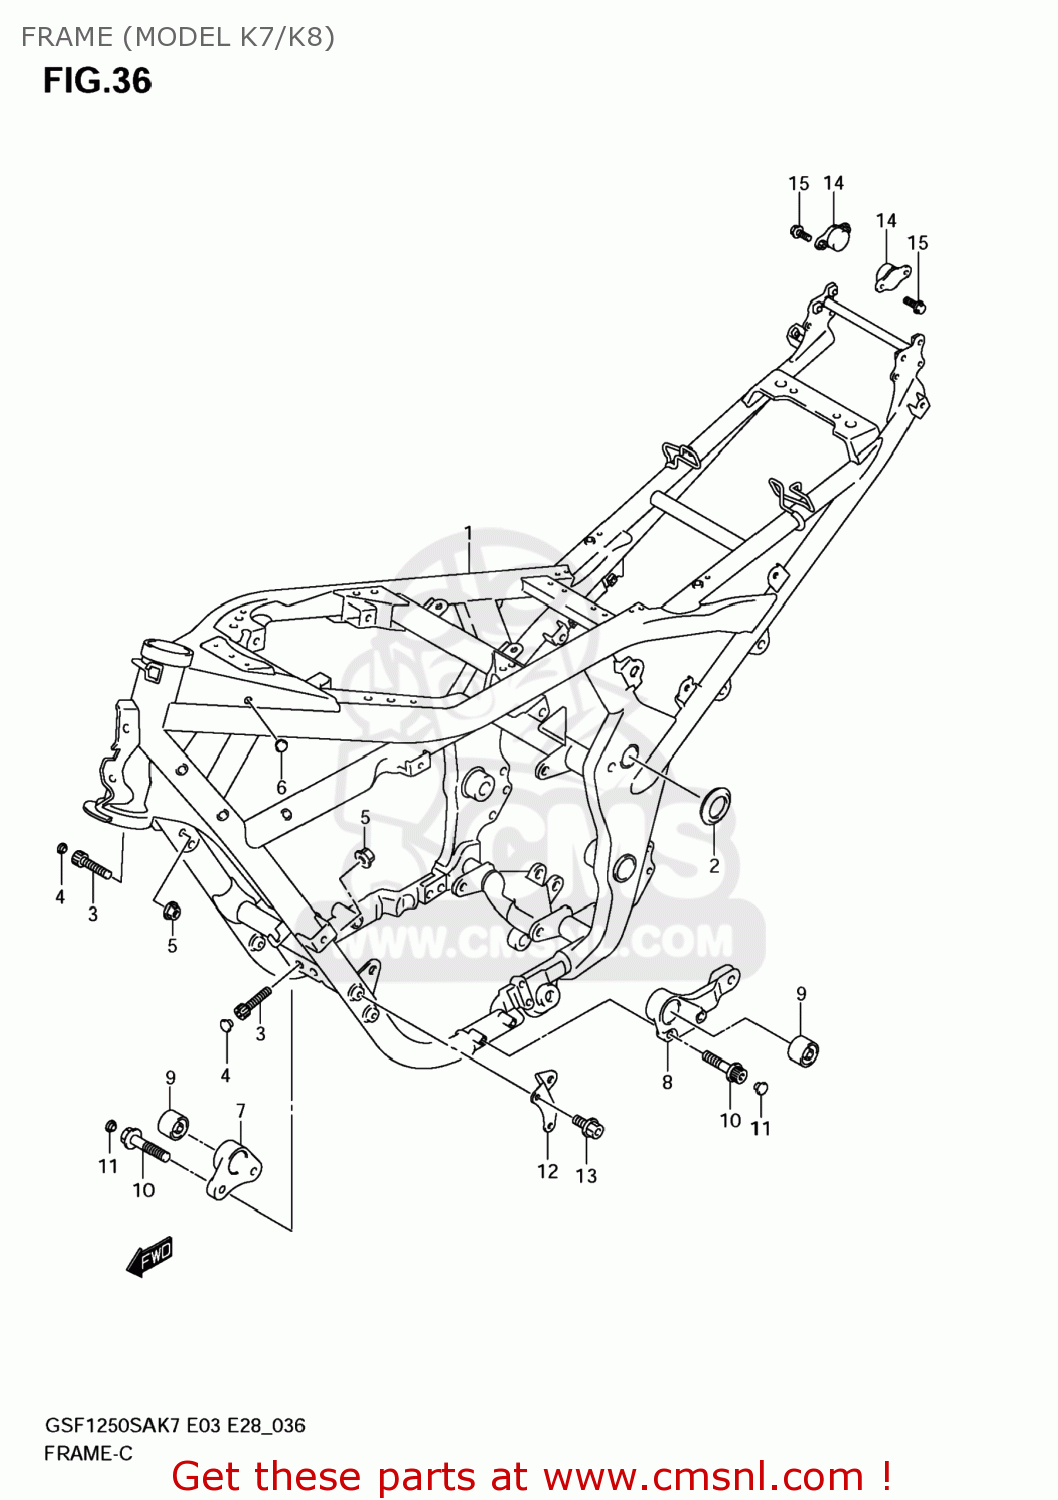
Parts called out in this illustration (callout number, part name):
1	FRAME SET
2	CAP,FRAME PIVO
3	BOLT(10X37)
4	CAP(OD:12)
5	NUT
6	PLUG(OD:17)
7	BRACKET,ENGINE MOUNTING NO.2,R
8	BRACKET,ENGINE MOUNTING NO.2,L
9	BUSH,ENG MOUNTING NO.2
10	BOLT(8X28)
11	CAP(OD:10)
12	BRACKET,ENGINE MOUNTING FR
13	BOLT
14	DAMPER,FRAME
15	BOLT
